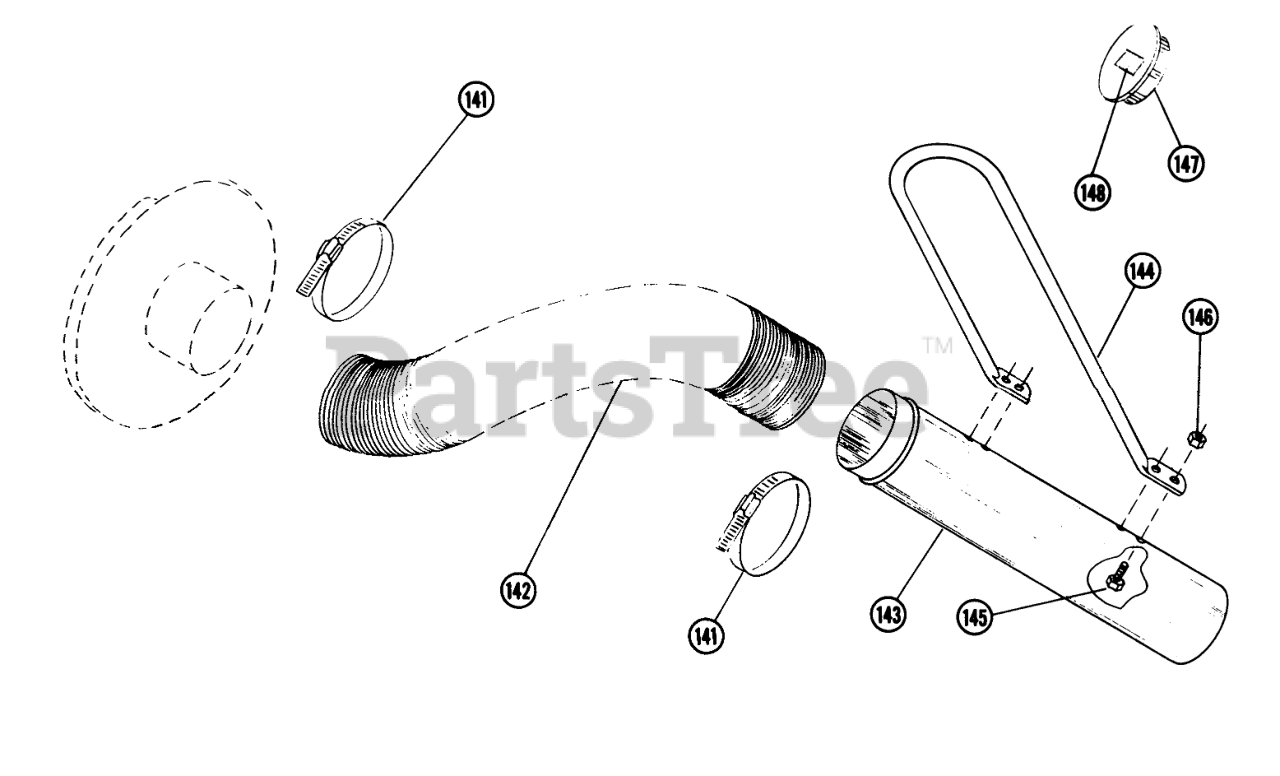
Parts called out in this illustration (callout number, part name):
141	CLAMP
142	10- Lg. Plastic Hose
143	Nozzle
144	Nozzle Handle
145	Bolt
146	Nut
147	Plug, Nozzle
148	Decal, Warning
